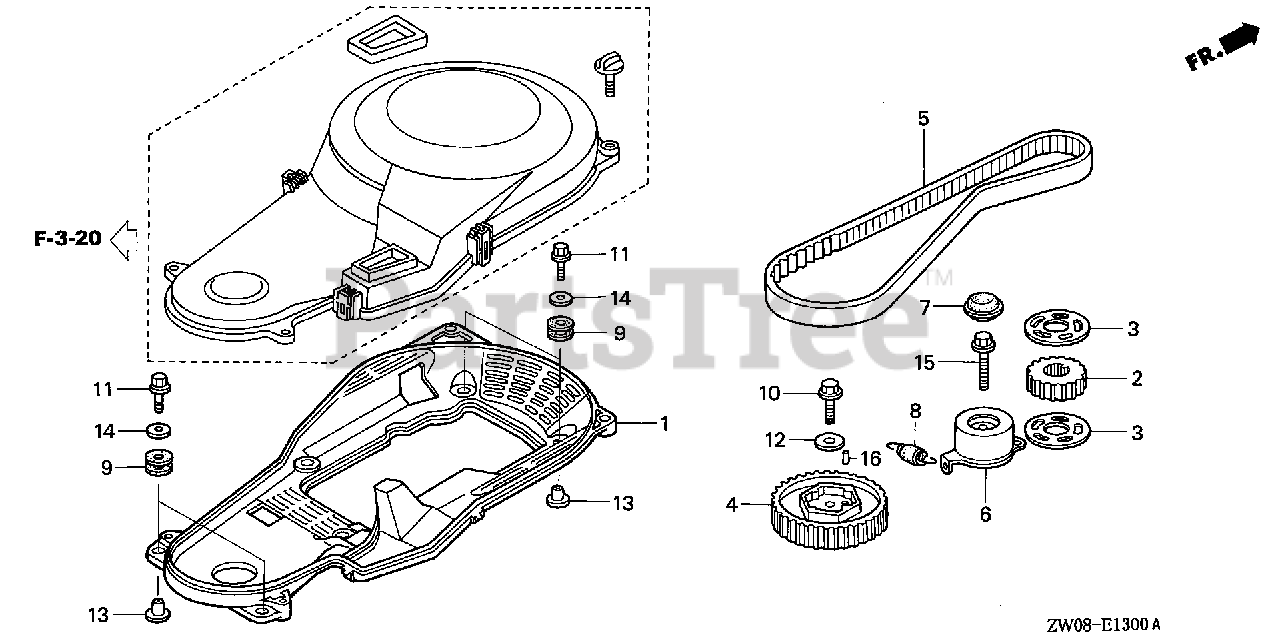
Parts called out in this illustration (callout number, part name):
1	COVER, TIMING BELT (LOWER)
2	PULLEY, TIMING BELT DRIVE
3	PLATE, TIMING BELT GUIDE
4	PULLEY, TIMING BELT DRIVEN
5	BELT, TIMING
6	TENSIONER, TIMING BELT
7	CAP, TIMING BELT TENSIONER
8	SPRING, TIMING BELT ADJUSTING
9	GROMMET, CASE (LOWER)
10	BOLT, FLANGE (10X32)
11	BOLT, FLANGE (6X25)
12	WASHER (10X28X5)
13	COLLAR, MODULE IGNITION CONTROL CASE (CDI)
14	WASHER, PLAIN (6MM)
15	BOLT, FLANGE (10X45)
16	ROLLER (4X10)
